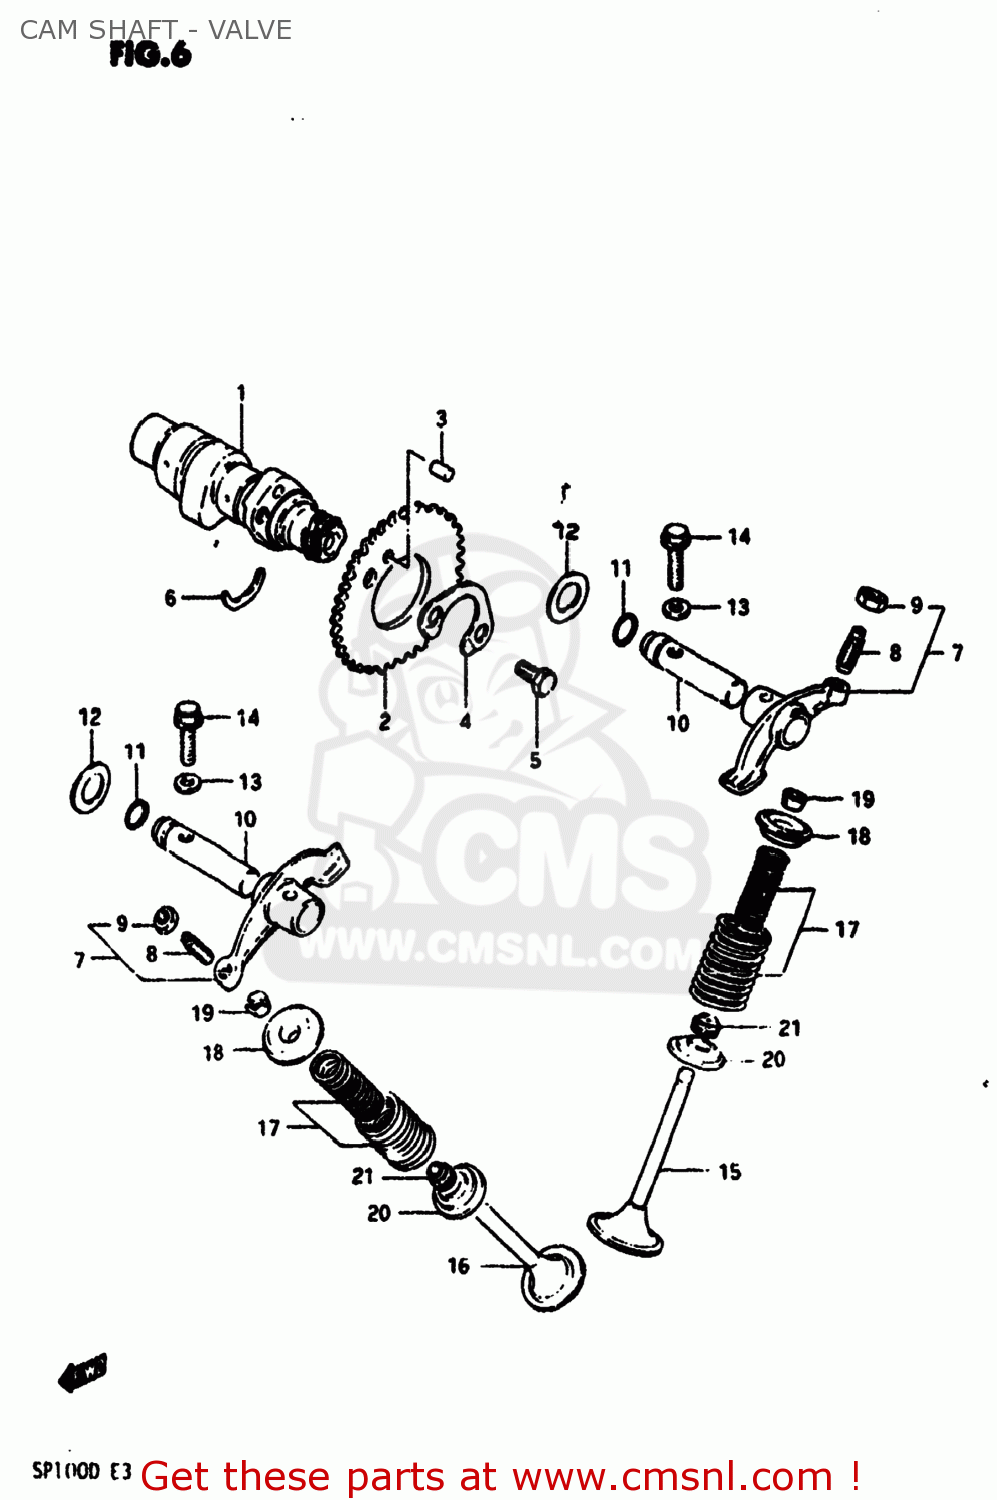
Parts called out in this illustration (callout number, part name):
1	CAMSHAFT
2	SPROCKET,CAMSHAFT
3	PIN(5X8)
4	WASHER,SPROCKET
5	BOLT(6X10.5)
6	C RING
7	ARM,VALVE ROCKER
8	SCREW,TAPPET ADJUSTING
9	NUT,ADJUSTING SCREW
10	SHAFT,VALVE ROCKET
11	O-RING
12	WASHER
13	GASKET(6.2X11X1).2 (NAS)
14	BOLT
15	VALVE,INTAKE
16	VALVE,EXHAUST
17	SPRING SET,VALVE
18	RETAINER,VALVE SPRING
19	COTTER VALVE
20	SEAT,VALVE SPRING
21	OIL SEAL
